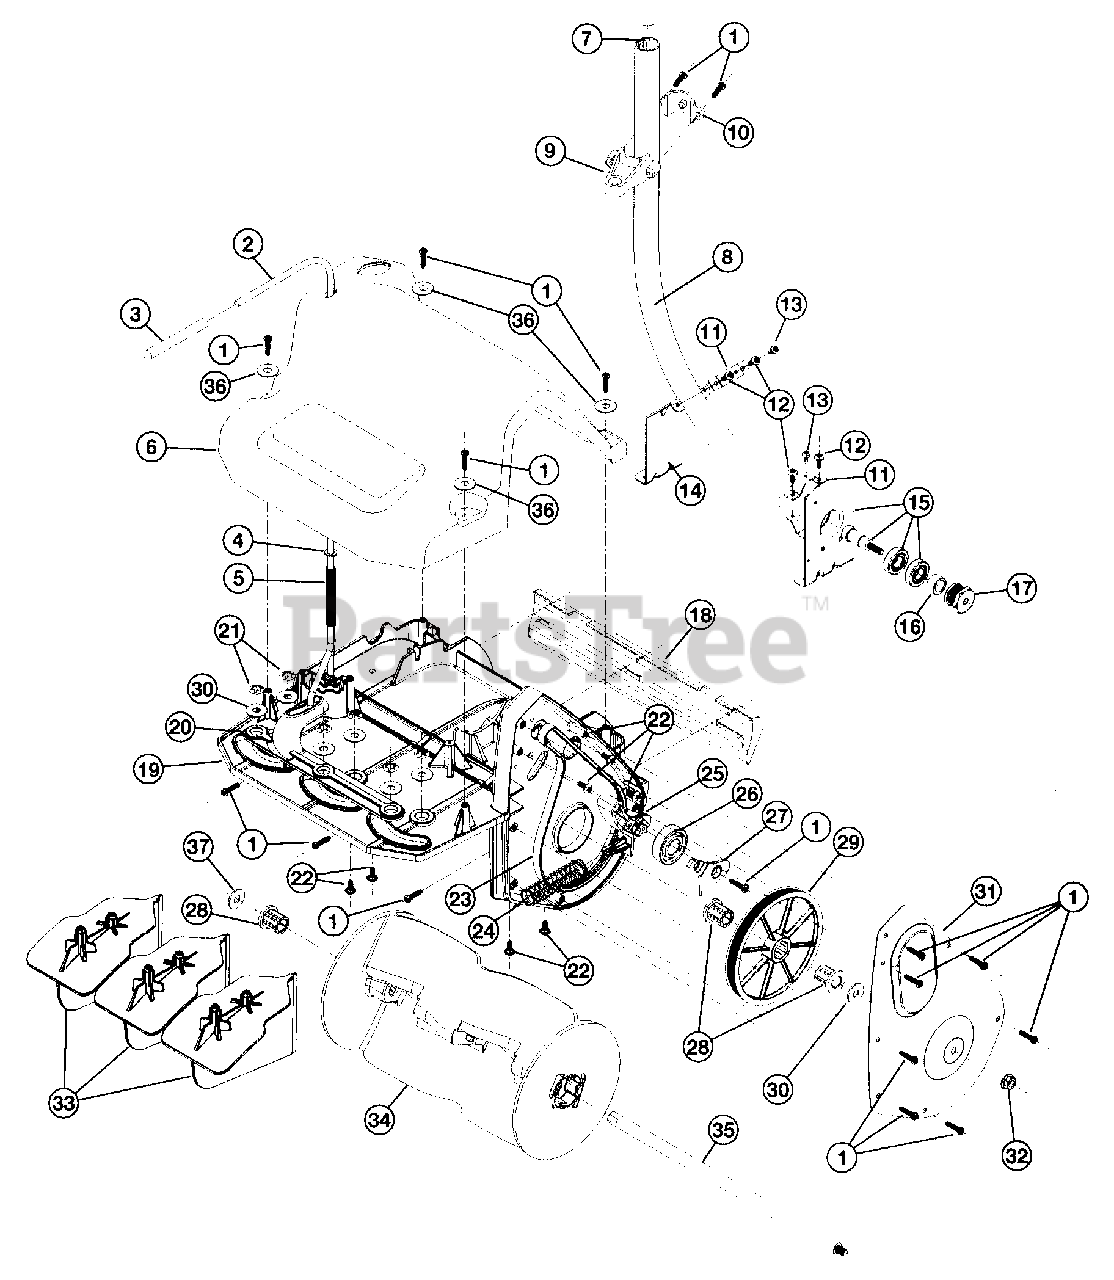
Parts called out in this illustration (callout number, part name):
2	Vane Control Handle
4	Washer
5	Spring
6	Cover
7	Flex Shaft
8	Drive Shaft Assembly
9	Clamp, LH
10	Clamp, RH
13	Screw, Anti-rotation
14	Drive Housing Bracket, RH
15	Drive Housing Bracket, LH
16	Spacer
17	Drive Pulley
18	Scraper
19	Snow Thrower Housing
20	Vane Control
21	Pushnut
23	Drive Belt
24	Spring
25	Idler Arm
26	Ball Bearing
27	Keeper
28	Flange Bearing
29	Driven Pulley
30	Washer
31	Belt Case Cover
32	Flange Lock Nut
35	Auger Shaft
